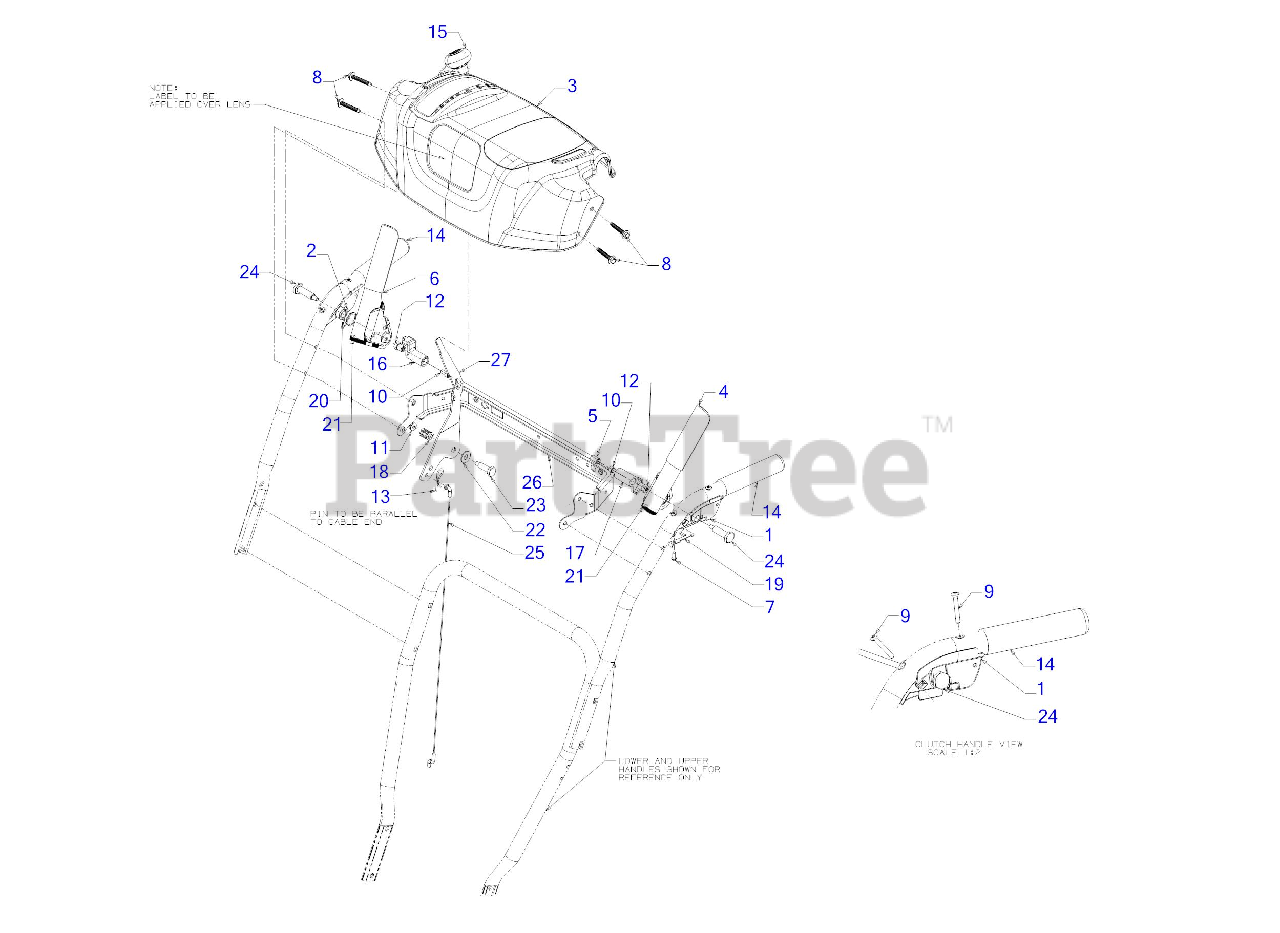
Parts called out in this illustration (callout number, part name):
1	CLUTCH LOCK HANDLE ASSEMBLY (LH)
2	CLUTCH LOCK HANDLE ASSEMBLY (RH)
3	HANDLE PANEL ASSEMBLY (BLACK)
4	HANDLE ASSEMBLY (LH)
5	PIVOT ROD
6	ENGAGEMENT HANDLE ASSEMBLY (RH) (RED)
7	SCREW #8-16 x .50
8	SCREW 1/4-20 x 1.625
9	SCREW #10-24 x 1.375
10	SCREW 1/4-20 x .50
11	FLANGE LOCK NUT
12	HEX NUT W/PATCH
13	INTERNAL COTTER PIN
15	SHIFT KNOB
16	LOCK PLATE
17	CLUTCH LOCK CAM
18	COMPRESSION SPRING
19	CLUTCH SPRING
20	TORSION SPRING
21	RUBBER BUMPER
22	FLAT WASHER
23	SHOULDER SCREW
24	SHOULDER SCREW .437 x 1.345 1/4-20
25	SPEED SELECTOR CABLE (PLASTIC)
26	HANDLE SUPPORT BRACKET
27	SHIFT LEVER
